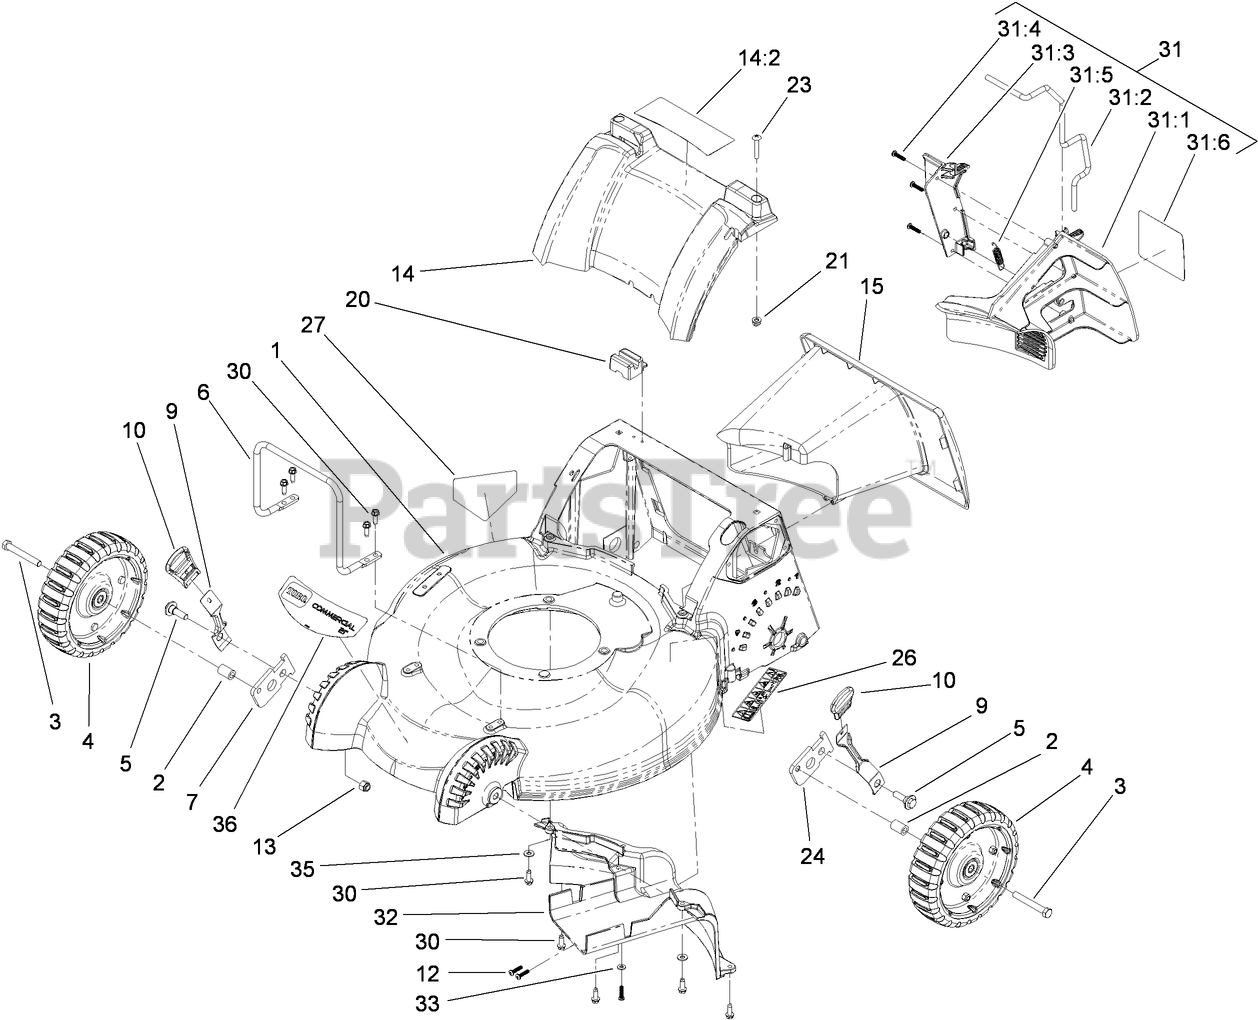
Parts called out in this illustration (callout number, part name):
1	HOUSING ASM
2	SPACER
3	SCREW-HH
4	8-INCH WHEEL ASM
5	SCREW-SHOULDER, HWH
6	GUARD-ENGINE
7	ARM-PIVOT, RH
9	ARM-SPRING, FRONT
10	KNOB-HOC
12	SCREW-PLASTITE
13	NUT-LOCK, NI
14	REAR COVER ASM
14:2	DECAL-WARNING
15	TUNNEL
20	MODULE-SWITCH
21	NUT-CLIP
23	SCREW-PTH
24	ARM-PIVOT, LH
26	DECAL-DANGER
27	DECAL-DANGER
30	SCREW-HWHTF
31	MULCH PLUG ASM
31:1	PLUG-MULCH, LH
31:2	LATCH-PLUG, MULCH
31:3	PLUG-MULCH, RH
31:4	SCREW-PLASTITE
31:5	SPRING-EXTENSION
31:6	DECAL-PLUG, MULCH
32	BAFFLE-REAR
33	WASHER-FLAT
35	WASHER-FLAT
36	DECAL-HOUSING, FRONT
